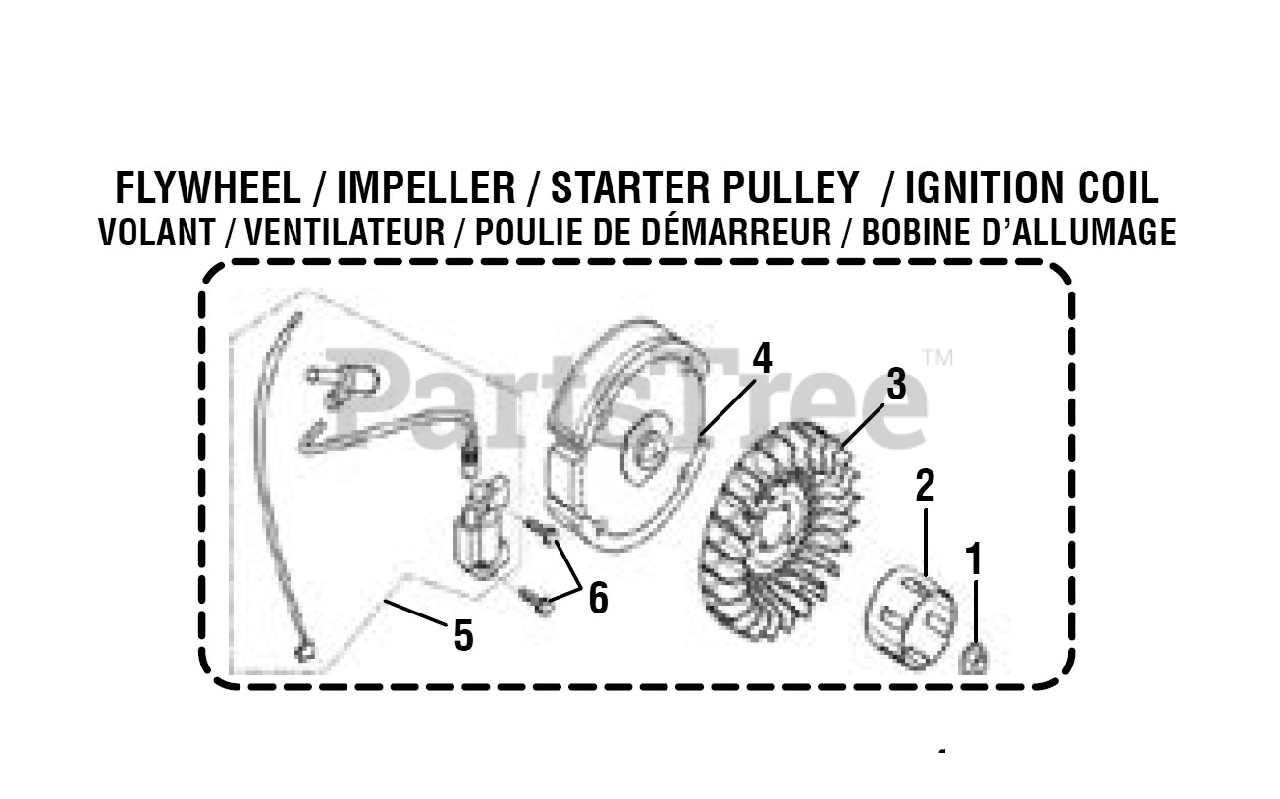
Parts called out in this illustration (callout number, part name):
1	Flywheel Nut
2	Starter Pulley
3	Impeller
4	Flywheel Assembly
5	Ignition Coil
